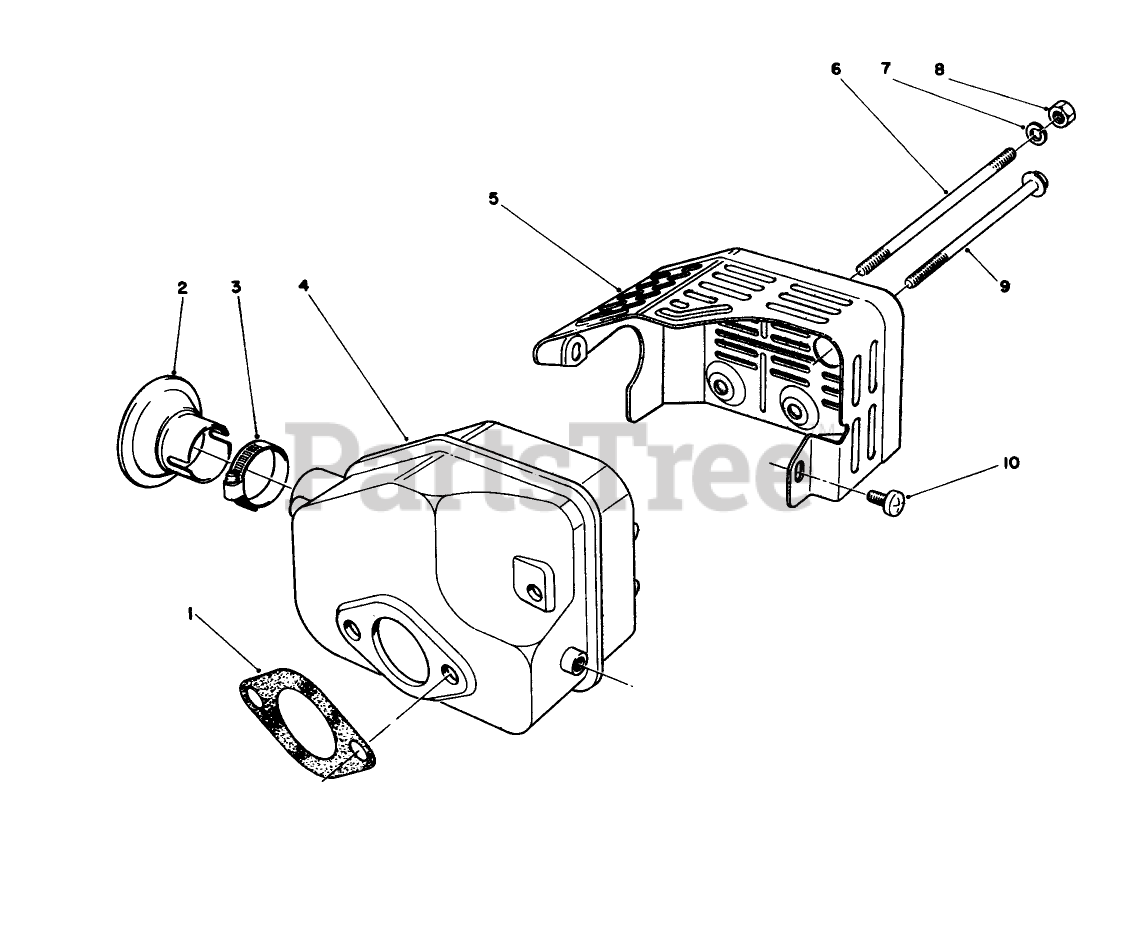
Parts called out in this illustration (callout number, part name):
1	GASKET
3	Clamp
4	MUFFLER
5	COVER-MUFFLER
7	WASHER-LOCK
10	SCREW
